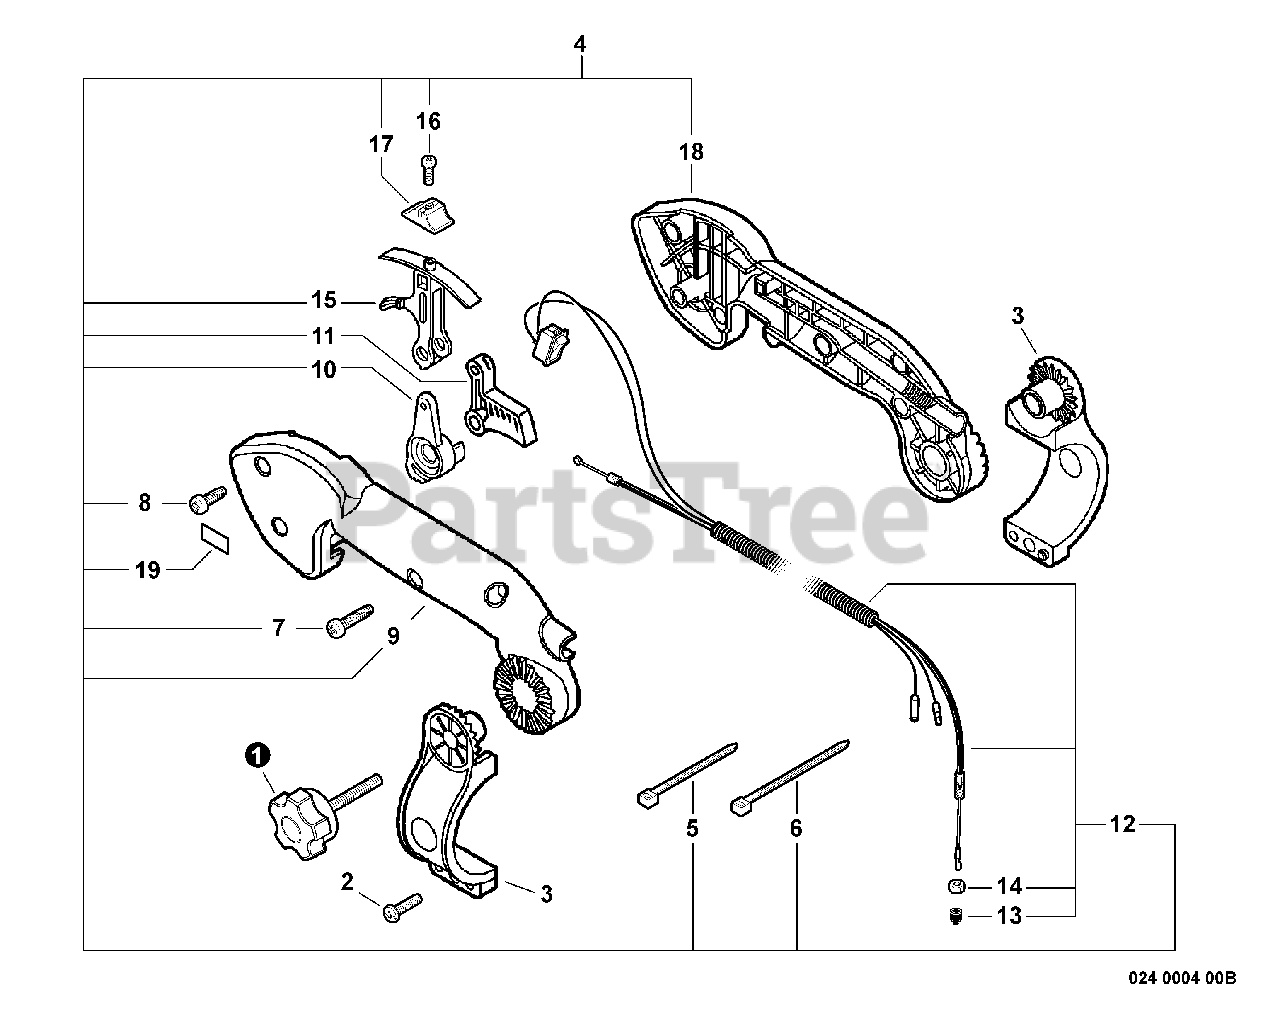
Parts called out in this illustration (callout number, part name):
1	KNOB, SCREW
2	SCREW, TAPPING 5×20
3	BRACKET KIT, HANDLE
4	CRUISE CONTROL KIT
5	STRAP, TIE
6	STRAP, TIE - LARGE
9	HANDLE, FRONT - LEFT
10	LEVER, THROTTLE
11	TRIGGER, THROTTLE
12	CONTROL CABLE ASSY
13	CAP, DUST
14	NUT, HEX M6
15	CONTROL, THROTTLE
16	SCREW 3×14
17	KNOB, CONTROL
18	HANDLE, FRONT - RIGHT
19	LABEL, CAUTION - IDLE
